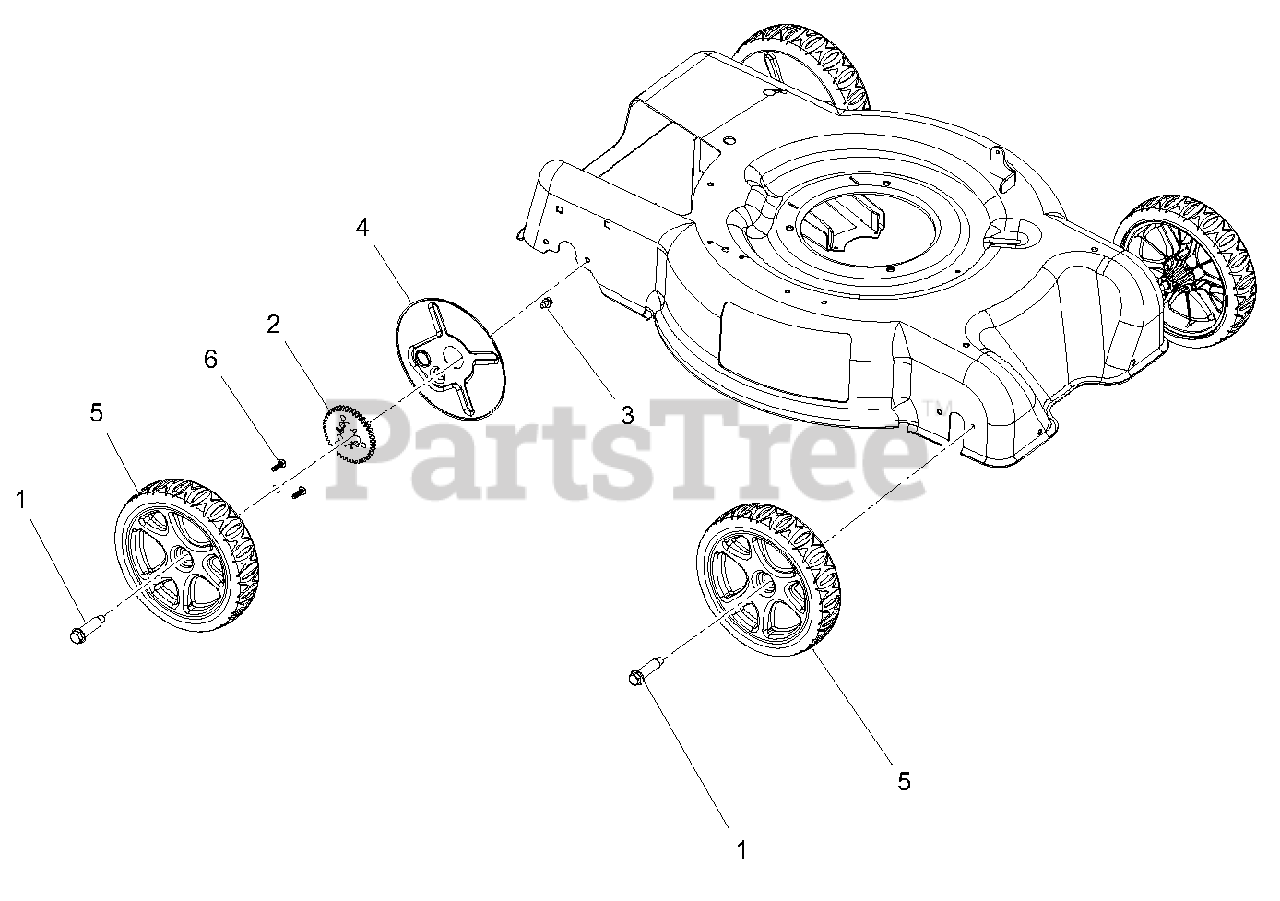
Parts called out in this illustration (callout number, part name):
1	BOLT, SHLDR
2	GEAR, WHEEL (911174, 178)
3	SCR-TAP .25-20X.37 HWH YWZ TR (911174, 178)
4	COVER, WHEEL - ARIENS LM SPECIAL (911174, 178)
5	WHEEL, LM - 2013 SPECIAL
6	SCR-TAP #12-14X.75 PLASTITE BLZC (911174, 178)
